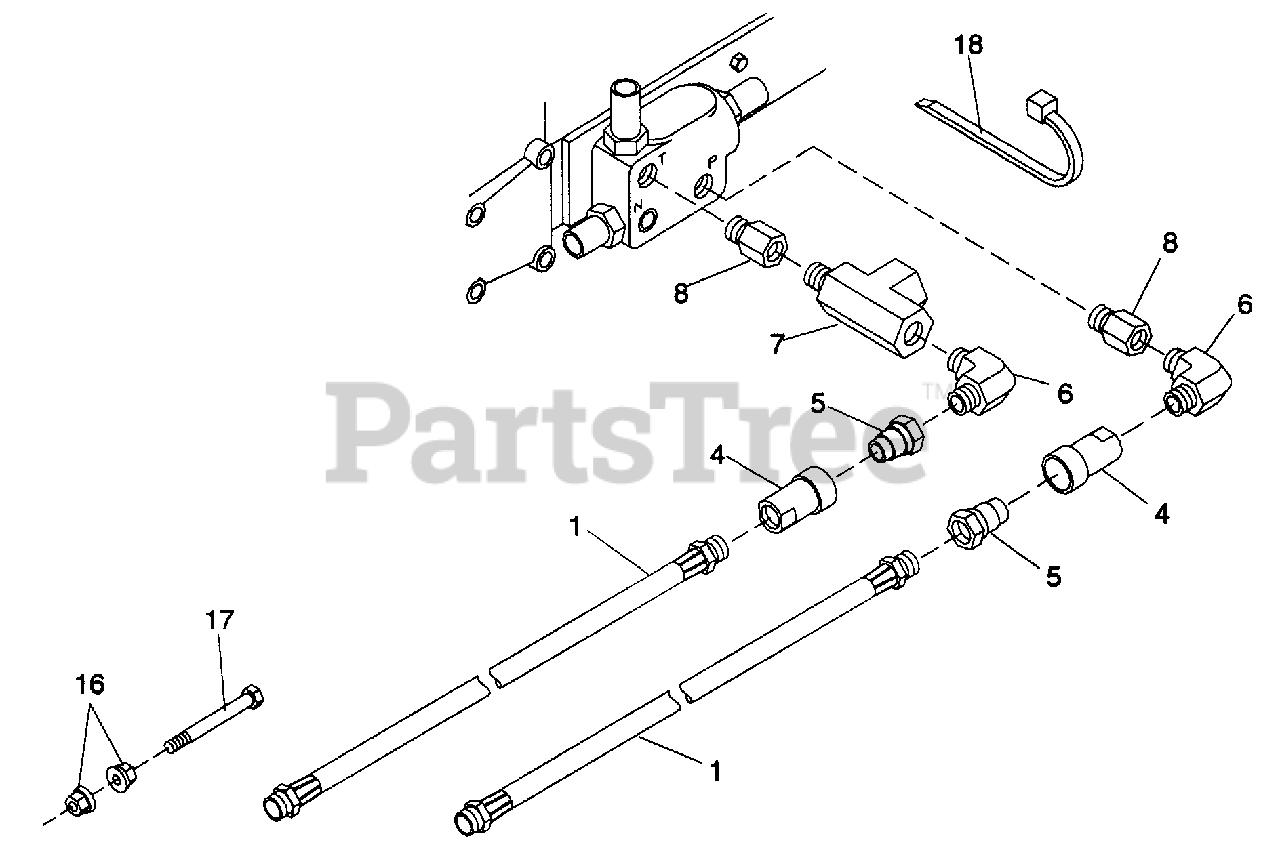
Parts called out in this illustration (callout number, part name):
1	Hose, 3/8 112 3/4 SAE M 3/8 NPT M
4	Quick coupler, 3/8 NPT female
5	Quick coupling, 3/8 NPT male
6	Elbow, Male 3/8 NPT x 90°
7	Run tee, 3/8 NPT
8	Adapter, 3/8 BSTP Male 3/8 NPT
16	1/4 NC Flanged locknut
17	1/4 NC x 4 Hex head cap screw GR5
18	Hydraulic hose tie, 7" long
